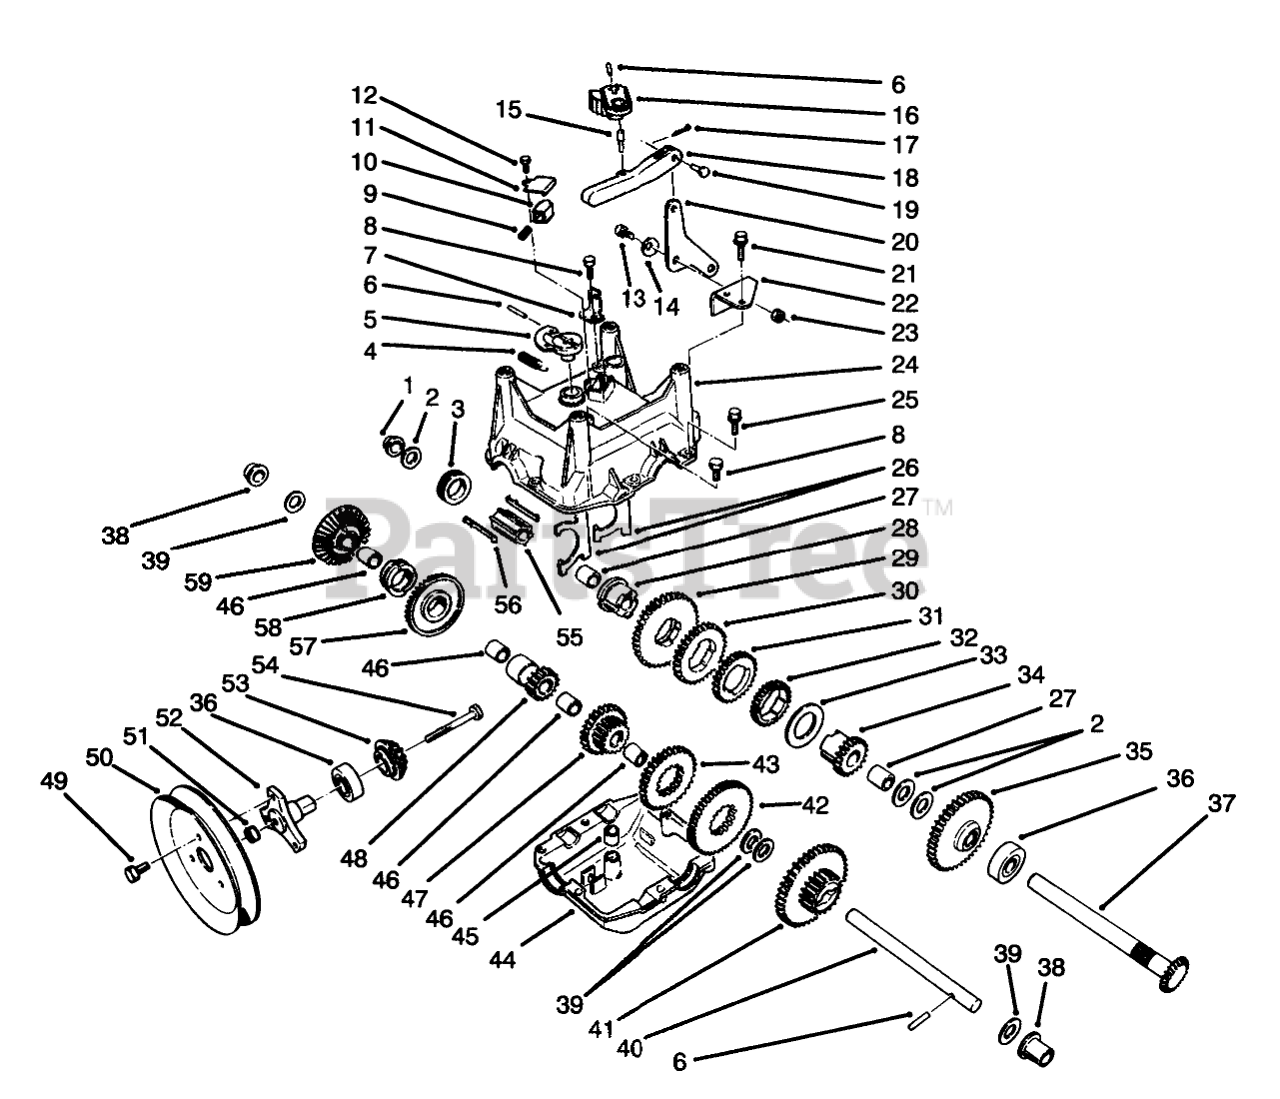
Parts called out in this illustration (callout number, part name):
1	BUSHING-FLANGE, OUTPUT
2	BEARING-THRUST
3	COLLAR-SHIFT
4	SPRING-EXTENSION
5	LEVER
6	PIN-SPRING
7	BRACKET-CABLE
8	SCREW-HWH
9	SPRING-DETENT
10	BUTTON-DETENT
11	COVER-DETENT
12	SCREW-HWH
13	SCREW-SHOULDER
14	WASHER-CURVED
15	PIN-LINK, GEAR SHIFT
16	LEVER-SHIFT, GEAR
17	PIN-COTTER
18	LINK-SHIFT, GEAR
19	PIN-CLEVIS
20	BELLCRANK
21	SCREW-HWH
22	BRACKET-BELLCRANK
23	NUT-LOCK, NI
24	GEARCASE-UPPER, CASING
25	SCREW-HWHTF
26	YOKE-SHIFT
27	BUSHING-OUTPUT
28	SLEEVE-GEAR
29	GEAR-45 T
30	GEAR-34 T
31	GEAR-27 T
32	GEAR-29 T
33	WASHER-THRUST
34	GEAR-SLEEVE, 19 T
35	GEAR-41 T
36	BEARING-BALL
37	SHAFT-OUTPUT
38	BUSHING-INTERMEDIATE
39	WASHER-THRUST
40	SHAFT-INTERMEDIATE
41	GEAR-19/41 T
42	GEAR-51 T
43	GEAR-33 T
44	GEARCASE-LOWER, CASING
45	BUSHING-YOKE
46	Bushing-Output
47	GEAR-26 T
48	GEAR-BEVEL, 15 T
49	SCREW
50	TRACTION-SHEAVE, HALF
51	NUT-HHF
52	HUB-PULLEY
53	PINION-BEVEL
54	SCREW-HH
55	SLEEVE-SHIFT
56	KEY-SHIFT
57	GEAR-BEVEL, 36 T
58	COLLAR-SHIFT
59	Gear-Bevel Reverse 36T (Incl. Ref. #46)
